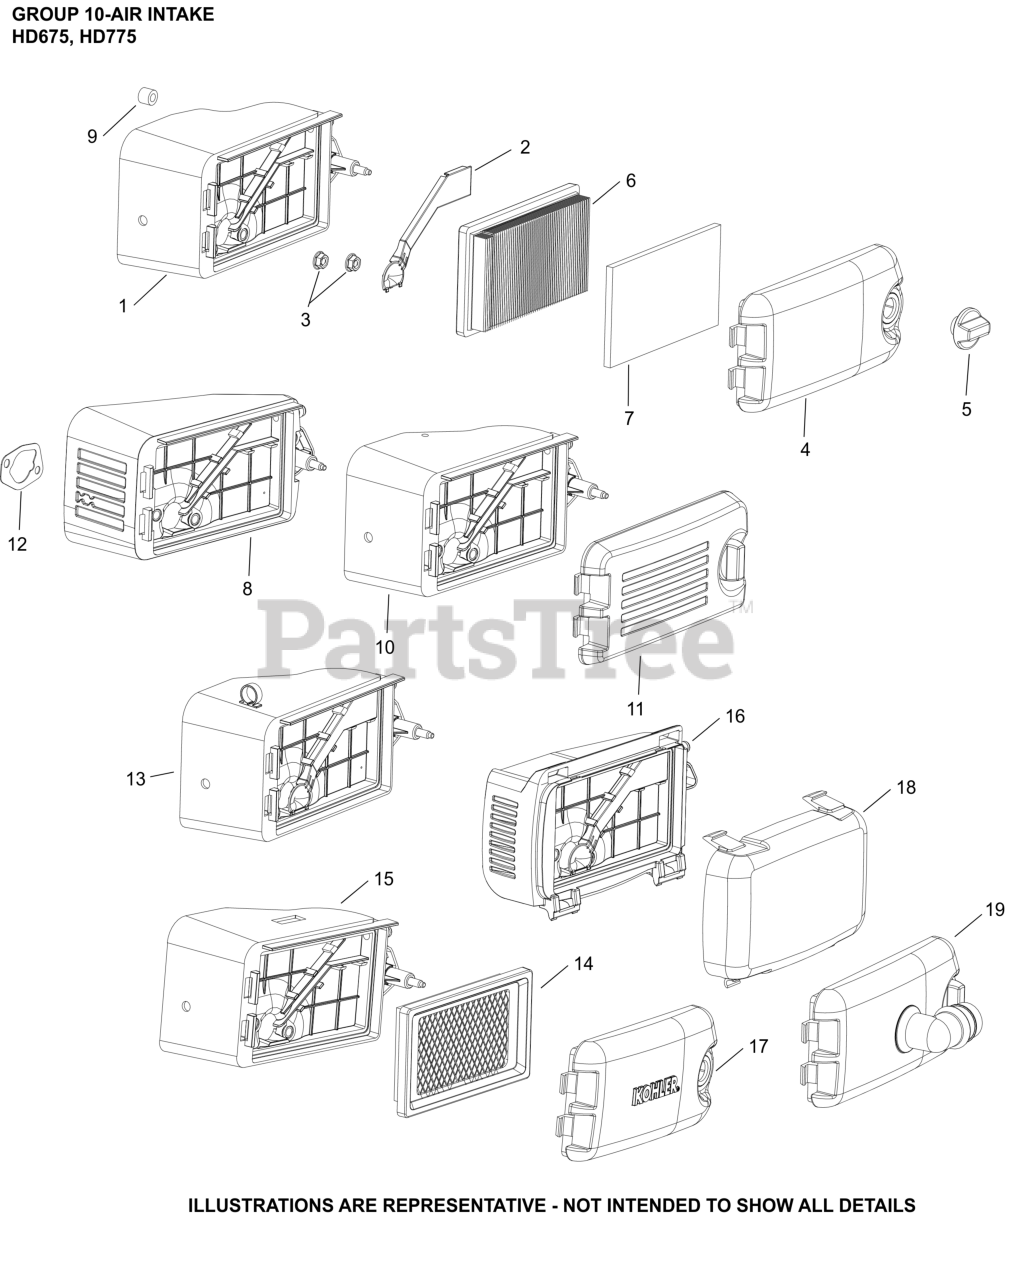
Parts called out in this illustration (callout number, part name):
1	AIR CLEANER BASE-USE 14 094 23-S
2	COVER, A/C BASE (BREATHER GAS)
4	COVER, AIR CLEANER
5	KNOB-USE 14 341 07-S
6	ELEMENT, AIR FILTER
7	ELEMENT, PRE-CLEANER
12	GASKET, AIR CLEANER BASE
